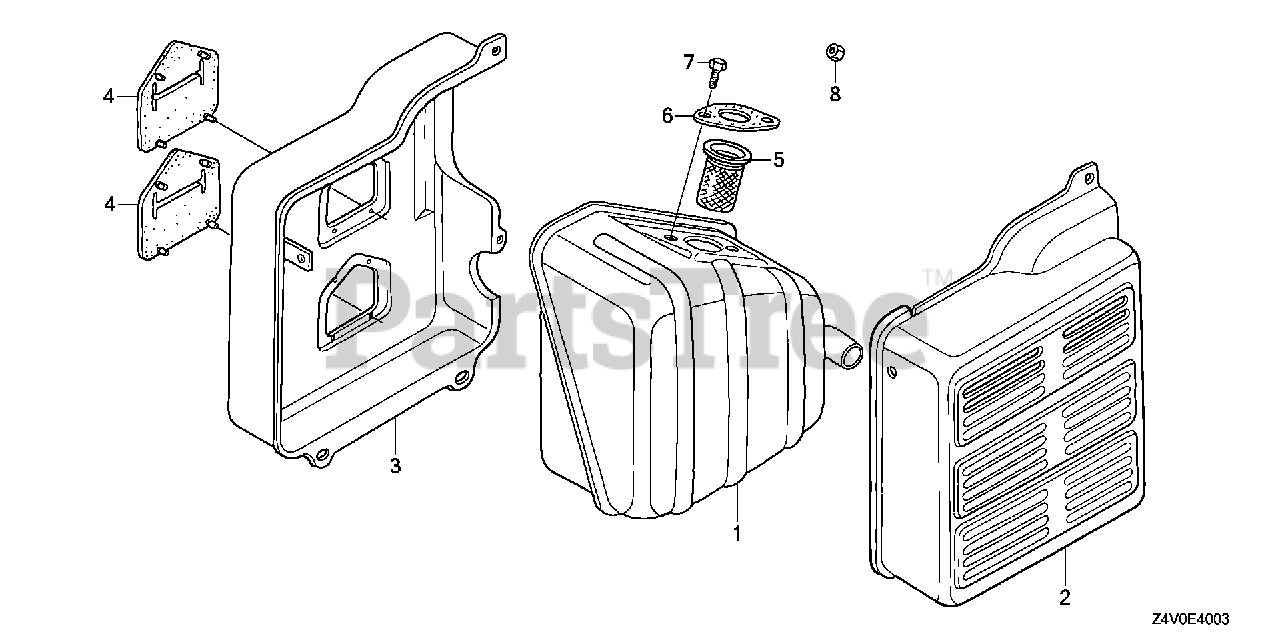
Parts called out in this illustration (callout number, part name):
1	MUFFLER
2	PROTECTOR, MUFFLER (OUTER)
3	PROTECTOR, MUFFLER (INNER) (DENYO)
4	SEAL, MUFFLER PROTECTOR
5	ARRESTER, SPARK
6	GASKET, MUFFLER
7	BOLT, HEX. (8X20)
8	NUT, HEX. (8MM)
